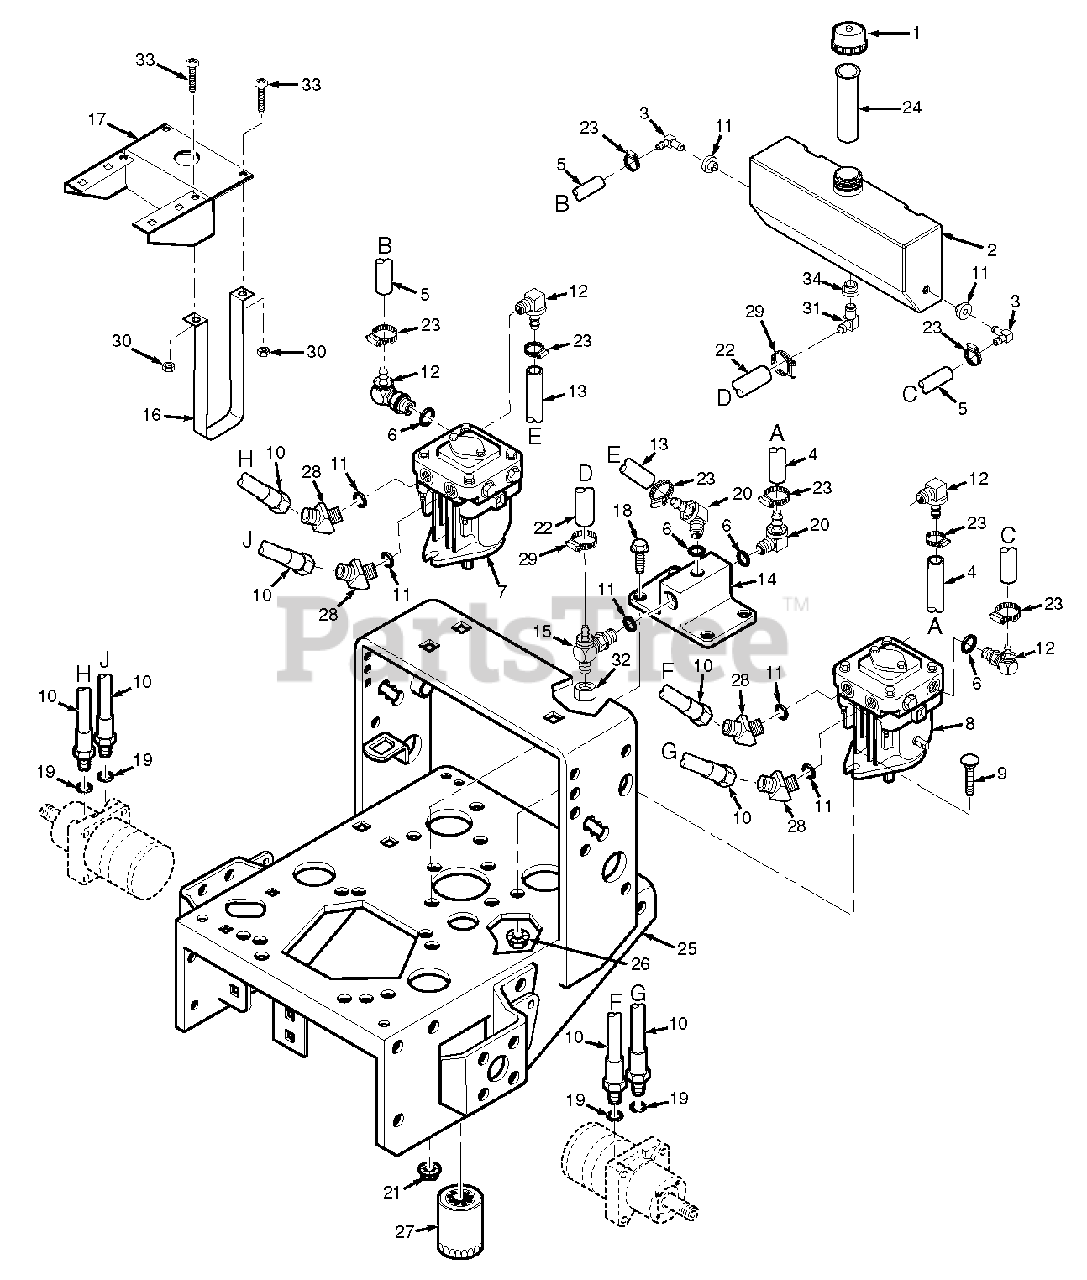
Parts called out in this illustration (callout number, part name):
1	Cap, Oil Reservoir
2	Oil Reservoir (With Fittings)
3	Fitting, 90 Degree - 3/8" Hose
4	Hose, 3/8" ID - 10-1/4" Long (Order By The Inch)
5	Hose, 3/8" ID - 7" Long (Order By The Inch)
6	O-Ring
7	Pump, PG-1JQQ-DY1X-XXXX (R.H.)
8	Pump, PG-1GQQ-DY1X-XXXX (L.H.)
9	Bolt, Carriage, 3/8-16 x 1.25"
10	Hose, Pump to Wheel Motor
11	Bushing, .56 Dia. Viton
12	Elbow, 7/16-20 O-Ring x 3/8" Hose
13	Hose, 3/8" ID - 11" Long (Order By The Inch)
14	Oil Filter Base
15	Tee, 3/8 O-Ring x JIC x 1/2" Hose
16	Strap, Hydraulic Tank
17	Bracket, Hydraulic Tank
18	Capscrew, 5/16-18 x .75" Serr. Flange
19	O-Ring
20	Elbow, 9/16 O-Ring x 3/8" Hose
21	Nut, 5/16-18 Serr. Flange
22	Hose, Formed 1/2" ID
23	Clamp, .69 max dia.
24	Tube, Filler Neck
25	Engine Deck (16" Wide) with Decals - Small Frame
25	Engine Deck (20" Wide) with Decals - Large Frame
26	Nut, 3/8-16 Serr. Flange
27	Oil Filter
28	Elbow, 45 Deg.-3/4-16 JIC Male x Male 3/4-16 O-Ring
29	Clamp, .87 max di.
30	Nut, 1/4-20
31	Fitting, 90 Degree - 1/2" Hose
32	Cap, 3/4-16
33	Screw, 1/4-20 x 2.0" Round Head Phillips
34	Bushing, .78 Dia. Viton
